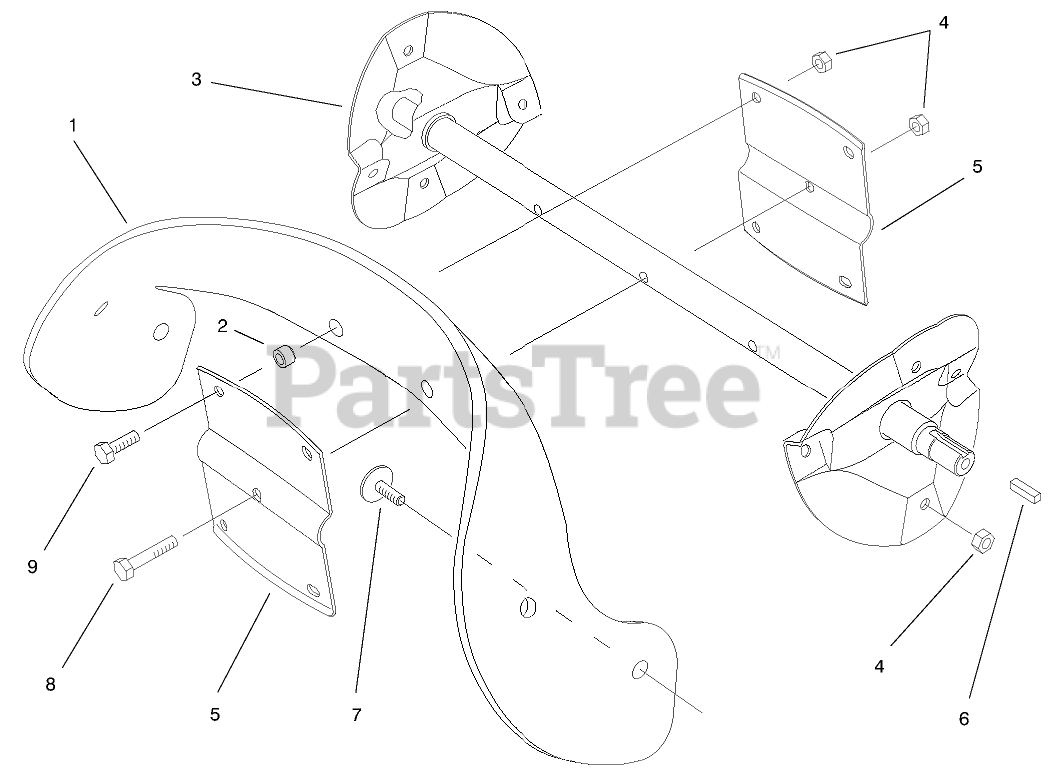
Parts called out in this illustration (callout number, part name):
1	Blade-Rotor
2	SPACER-BLADE, ROTOR
3	Rotor
4	NUT-LOCK, NI
5	HALF-ROTOR
6	KEY-SQUARE
7	SCREW
8	SCREW-HH
9	SCREW-HH
